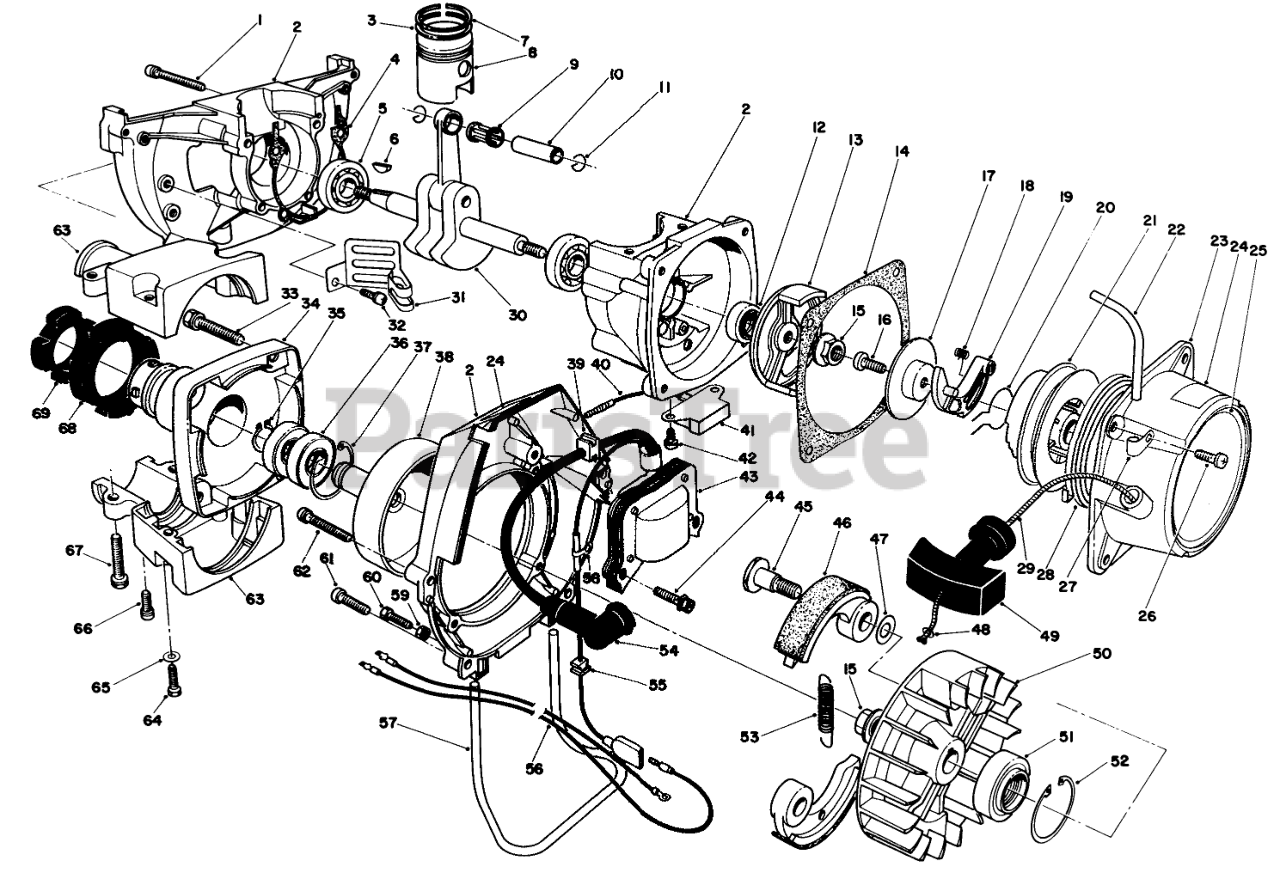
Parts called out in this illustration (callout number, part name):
1	SCREW & WASHER
2	Crankcase (Incl. Ref. #1, & 61)
3	RING,PISTON
4	GASKET,CASE
5	BALL BEARING
6	Key-Woodruff
7	RING,PISTON
8	Piston Set (Incl. Ref. #10)
9	BEARING, NEEDLE
10	PIN, PISTON
11	CLIP, PISTON PIN
12	Seal-Oil
13	PULLEY, STARTER
14	GASKET, STARTER
15	Nut-Conical
16	Screw
17	PLATE, FRICTION
18	SPRING, RETURN
19	RATCHET
20	SPRING, FRICTION
22	Tube-Fuel
23	Recoil-Starter (Incl. Ref. #13, 16-21, 24, 25, 28, 29, & 49)
24	DECAL-SURFACE, HOT
25	TORO DECAL
26	Screw
27	Clamp
28	SPRING, SPIRAL
29	Rope-Starter
30	Crankshaft (Incl. Ref. #6 & 9)
31	Clamp
32	Screw & Washer
34	CASE, CLUTCH
35	SNAP RING
36	BALL BEARING
37	SNAP RING
38	DRUM, CLUTCH
39	Grommet
40	WIRE, LEAD
41	Unit-Transistor (Incl. Ref. #40)
42	SCREW & WASHEROR
43	COIL, IGNITION
44	Bolt & Washer
45	BOLT,CLUTCH
46	Shoe-Clutch
47	WASHER
48	WASHER
49	Knob-Starter
50	FLYWHEEL
51	OIL SEAL
52	SNAPRING
53	SPRING
54	Cap-Plug
55	GROMMET
56	WIRE,LEAD
57	TANK GUARD
58	Clamp
61	Screw
62	Screw
63	VV2DER
65	Washer
66	SCREW & WASHER
67	BOLT-WASHER/ENG
68	RUBBER, CUSHION (A)
69	RUBBER, CUSHION (B)
